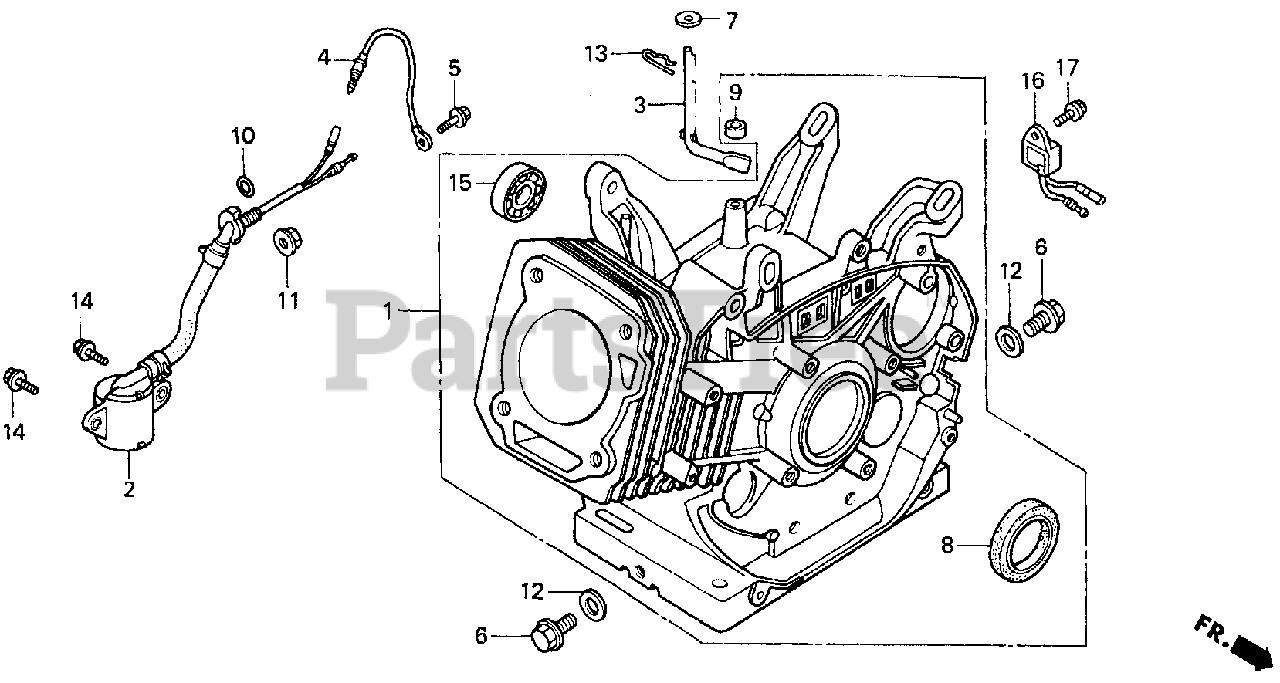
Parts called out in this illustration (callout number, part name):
1	CYLINDER ASSY. (SELFSTARTER+ALERT)
2	SWITCH ASSY., OIL LEVEL
3	SHAFT, GOVERNOR ARM
4	SUB-HARNESS
5	BOLT, FLANGE (6X12) (CT200)
6	BOLT, DRAIN PLUG
7	WASHER (8.2X17X0.8)
8	OIL SEAL (35X52X8)
9	OIL SEAL (8X14X5)
10	O-RING (13.5X1.5) (ARAI)
11	NUT, FLANGE (10MM)
12	WASHER, DRAIN PLUG (12MM)
13	PIN, LOCK (10MM)
14	BOLT, FLANGE (6X12)
15	BEARING, RADIAL BALL (6202)
16	ALERT UNIT, OIL
17	BOLT, FLANGE (6X12) (CT200)
